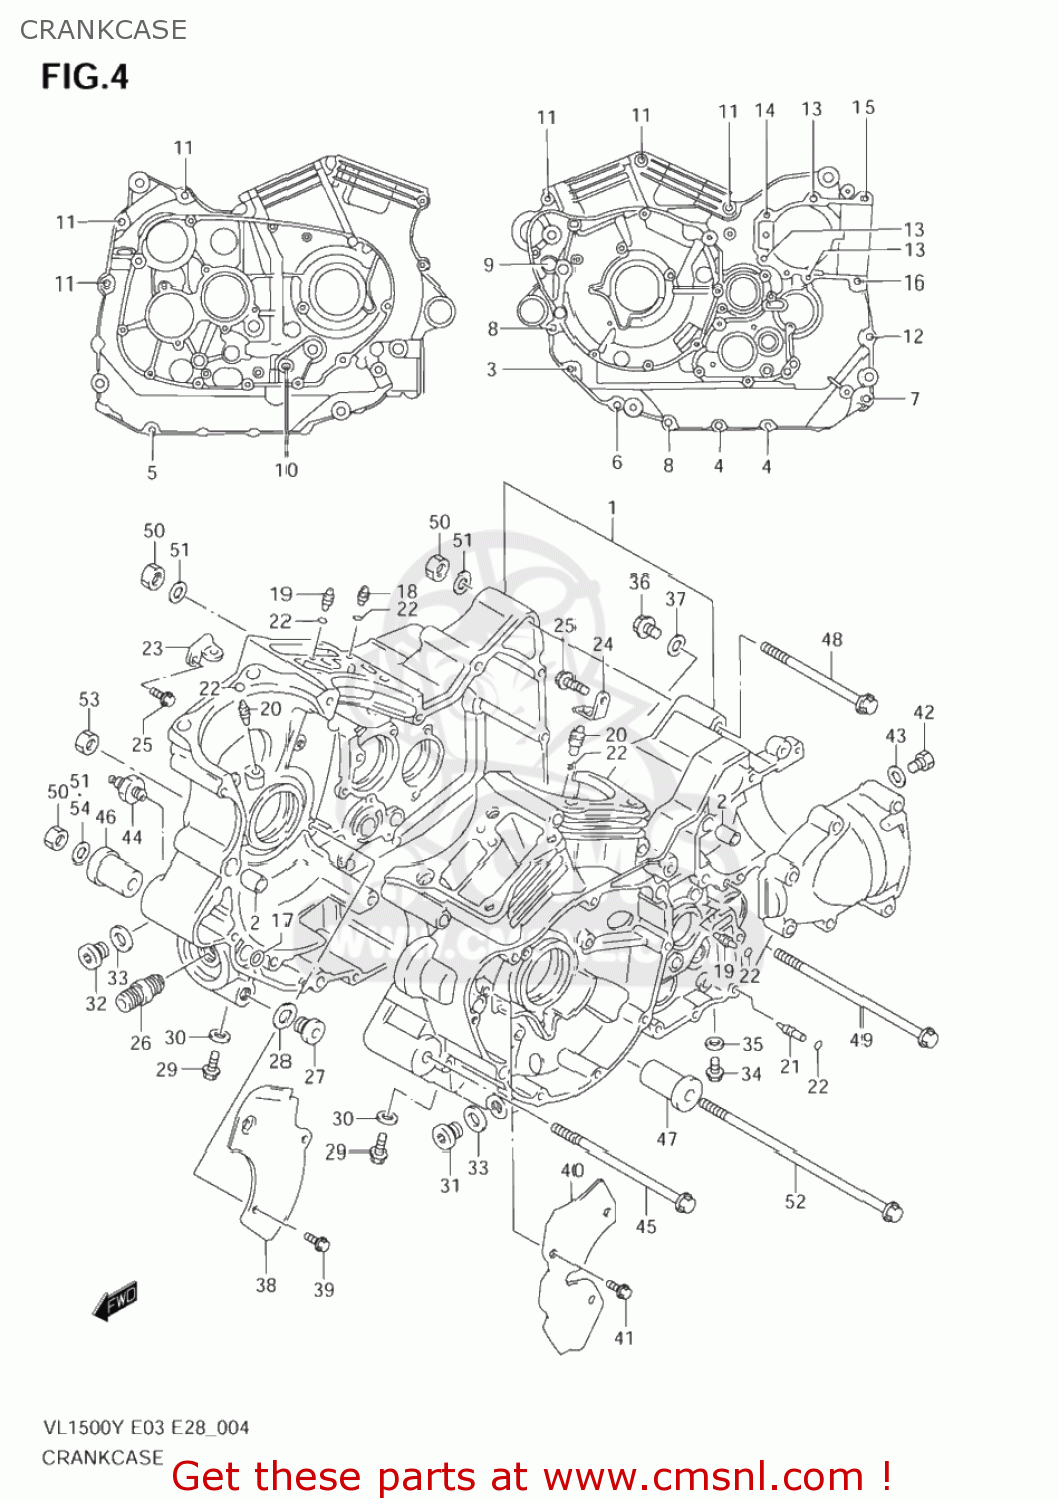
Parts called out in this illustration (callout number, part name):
1	CRANKCASE SET
2	PIN(8.4X11X20)
3	BOLT, HYDRAULIC UNIT NO.2
4	BOLT
5	BOLT
6	BOLT
7	BOLT
8	BOLT (8X70)
9	BOLT
10	BOLT(8X115)
11	BOLT(8X95)
12	BOLT (8X80)
13	BOLT
14	BOLT
15	BOLT
16	BOLT
17	O RING(D:1.9,ID:12.6)
18	JET(2.2)
19	JET,AIR(14)
20	JET,PISTON COOLING(0.8)
21	JET,MISSION OIL(1.4)
22	O RING(D:1.2,ID:4)
23	PLATE,PISTON JET FR
24	PLATE,PISTON JET RR
25	BOLT
26	UNION,OIL STAND
27	PLUG,16X8
28	GASKET(16X22X2) (NAS)
29	BOLT
30	GASKET(8.2X16X1) (NAS)
31	PLUG,14X12
32	PLUG(14X11.5)
33	GASKET(13.8X18.8X4.8) (NAS)
34	BOLT
35	GASKET(5.8X11X1.2) (NAS)
36	PLUG(12X10)
37	GASKET(12.1X16.2X3.7) (NAS)
38	PLATE,OIL SEPARATOR
39	BOLT(6X12)
40	PLATE,OIL SEPARATOR FR
41	BOLT
42	PLUG,12X20
43	GASKET(12.1X16.2X3.7) (NAS)
44	SWITCH ASSY,OIL PRESSURE
45	BOLT(10X205)
46	SPACER,ENG MTG
47	SPACER,ENGINE MOUNT(L27)
48	BOLT(10X140)
49	BOLT(10X160)
50	NUT
51	WASHER
52	BOLT(10X265)
53	NUT
54	WASHER (10.5X20X3.2)
